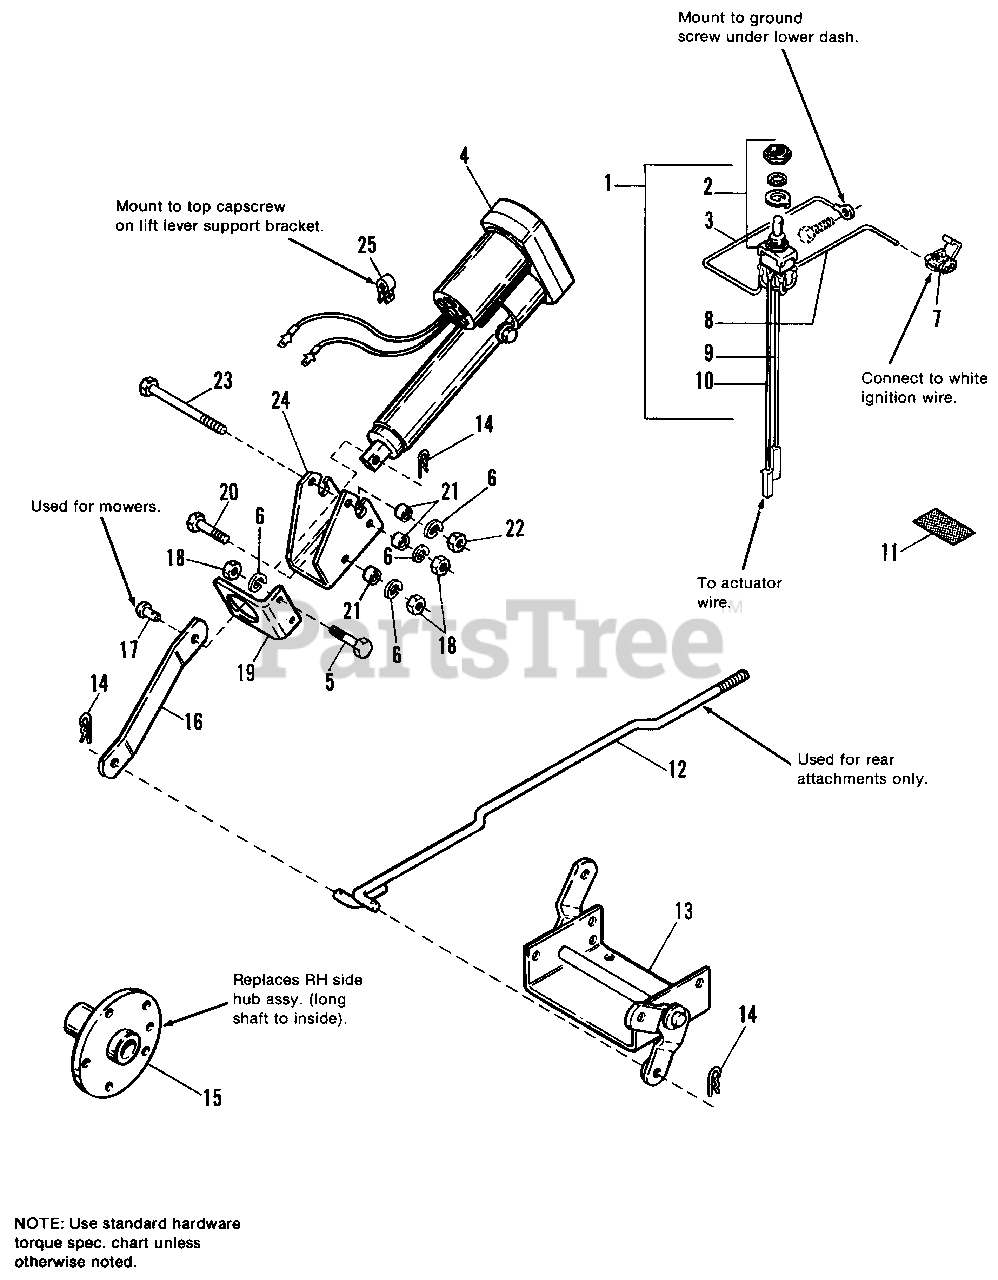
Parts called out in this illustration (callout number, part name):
1	HARNESS ASSY., Electric Lift
2	SWITCH, Electric
3	WIRE, Switch to Ground
4	POWER LIFT ASSY. (See pages 66 & 67 for parts breakdown.)
5	CAPSCREW, Hex Hd., 5/16-18 x 1
6	LOCKWASHER, 5/16
7	CONNECTORS, Self-Stripping
8	WIRE, Switch to Ignition
9	WIRE, Switch to Lift
10	WIRE, Switch to Lift
11	DECAL, Lift Swtich
12	ROD ASSY., Lift
13	ROD ASSY., Lift
15	HUB ASSY.,Wheel
16	LINK, Actuator
18	NUT, Hex, 5/16-18
19	BRACKET, Actuator, Front
20	CAPSCREW, Hex Hd., 5/16-18 x 1-1/2
22	NUT, Hex, Lock 5/16-18
23	CAPSCREW, Hex, Hd., 5/16-18 x 4-1/2
24	BRACKET, Actuator
25	CLAMP, Insulated
